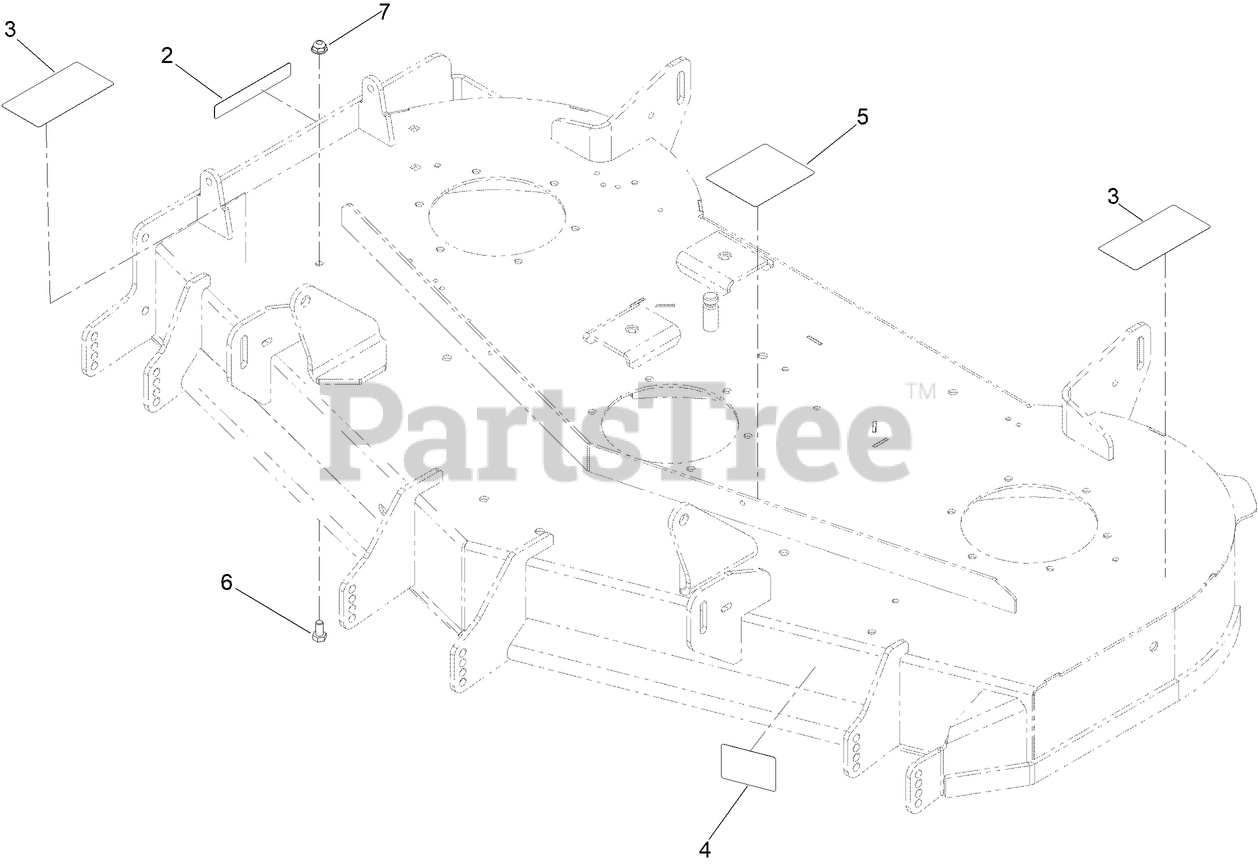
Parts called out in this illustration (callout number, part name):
2	DECAL-DANGER
3	DECAL-DANGER, DECK
4	DECAL-SCALP, ANTI
5	DECAL-ROUTING, BELT
6	SCREW-HH
7	NUT-HF
